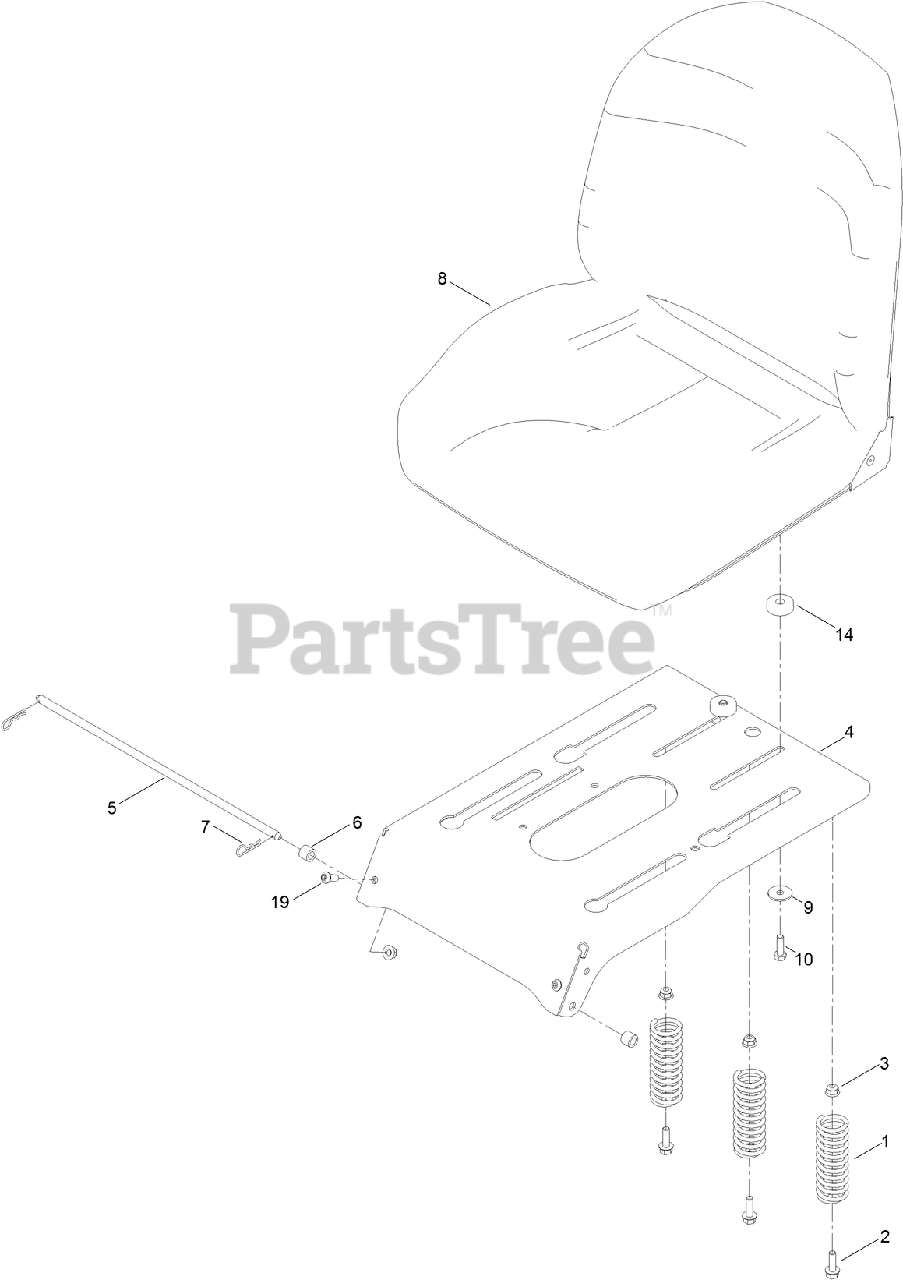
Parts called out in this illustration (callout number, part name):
1	SPRING-COMPRESSION
2	SCREW-HHF
3	NUT-HF, NI
4	PAN-SEAT, DELUXE
5	ROD-STOP
6	BUSHING-LEVER, LIFT
7	PIN-COTTER
9	WASHER-PIVOT
10	SCREW-HH
14	BUSHING-SLIDE, SEAT
19	SCREW-HSBH
